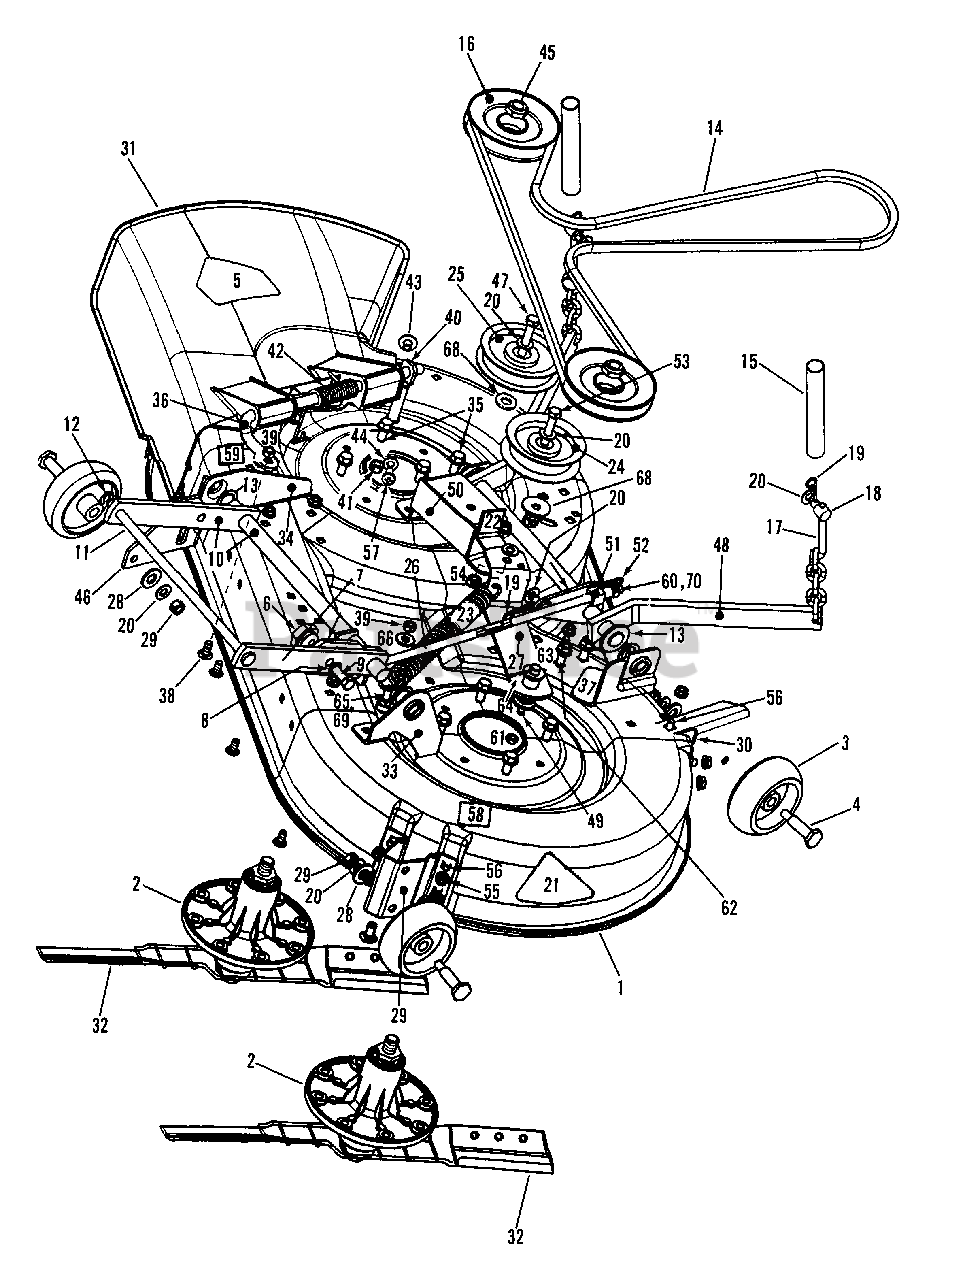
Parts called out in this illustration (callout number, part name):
1	DECK, 38"
2	ASSEMBLY, Spindle
3	WHEEL 4 x 1-1/2" Offset
4	SHOULDER BOLT, 3/8-24
5	DECAL, CPSC-Heavy Adhesive
6	ECCENTRIC, Leveling
7	LIFT ARM, Front
8	WASHER, 3/8" Internal Tooth Lock
9	SCREW, 3/8-24 x 1-1/4" Hex Head Cap. Grade 5
10	LIFT ARM, Front
11	ROD, Deck Support
12	RING, .438 External Retaining
13	WASHER, 3/4" I.D.x 1-1/8" Flat
14	V-BELT, HA Section
15	COVER, Chain
16	PULLEY, 4-1/2" O.D., A/B Groove
17	ADJUSTER, Chain
18	SWIVEL, Adjustable
19	HAIR PIN, 3/32 x 1-1/2"
20	WASHER, 3/8" Flat
21	DECAL, 38 Inch
22	BELT GUIDE, 38/42
23	SPRING, Extension
24	IDLER, 4" O.D. Flat
25	IDLER, 4-1/8" O.D. Flat
26	ROD, Cutter Deck Timing
27	ARM, Idler
28	WASHER, 1/2" x 1-1/16" Flat
29	BRACKET, Gage Wheel
30	BRACKET, L.H. Wheel
31	CHUTE, Discharge
32	BLADE, 19-1/2"
33	BRACKET, 38 Deck Lift, L.H.Front
34	BRACKET, 38 Deck Lift, R.H.Front
35	SCREW, 3/8-16 x 3/4" Hex Washer Self-Tap
36	ROD, Pivot, Side Discharge
37	BRACKET, L.H. Rear Lift Arm
38	BOLT, 5/16-18 x 3/4" Cam, Grade 5
39	NUT, 5/16-18 Hex Center Lock, Grade 5
40	ROD, Mounting, Side Discharge
41	NUT, 3/8-16 Hex Flange Lock
42	SPRING, Torsion-Side Discharge
43	TEENUT, 5/16-18 Thread
44	WASHER, 5/16" I.D. x 11/16", Flat
45	NUT, 5/8-18 Lock
46	BRACKET, Gage Wheel
47	SCREW, 3/8-16 x 2", Hex Head Cap, Grade 5
48	TIMING ARM, Rear
49	STUD, Idler
50	BRACKET, Stationary Idler
51	SWIVEL, Brake Link
52	HAIR PIN, #13
53	SCREW, 3/8-16 x 1-3/4" Hex Head Cap, Grade 5
54	NUT, 3/8-16 Hex Ctr Lock, Gr.5
55	NUT, 5/16-18 Hex Flange Lock, Grade 5
56	BOLT, 5/16-18 x 5/8" Carriage, Grade 5
57	SCREW, 5/16-18 x 5/8" Pan Head
58	DECAL, Caution
59	DECAL, Caution
60	NUT, 3/8-16 Hex Ctr. Lock. Grade 5
61	NUT, 5/16-24 Hex Center Lock
62	BOLT, 3/8-16 x 3/4" Carr., Gr. 5
63	WASHER, 1/2" I.D.x 1-1/16" O.D. Flat
64	COTTER-PIN, 3/32 x 3/4"
65	BOLT, 5/16-18 x 1-1/2" Carr., Gr. 5
66	WASHER, 3/8" I.D. x 7/8" O.D. Flat
68	WASHER, Cone
69	SPACER, 11/32"
70	SPACER, 25/64"
